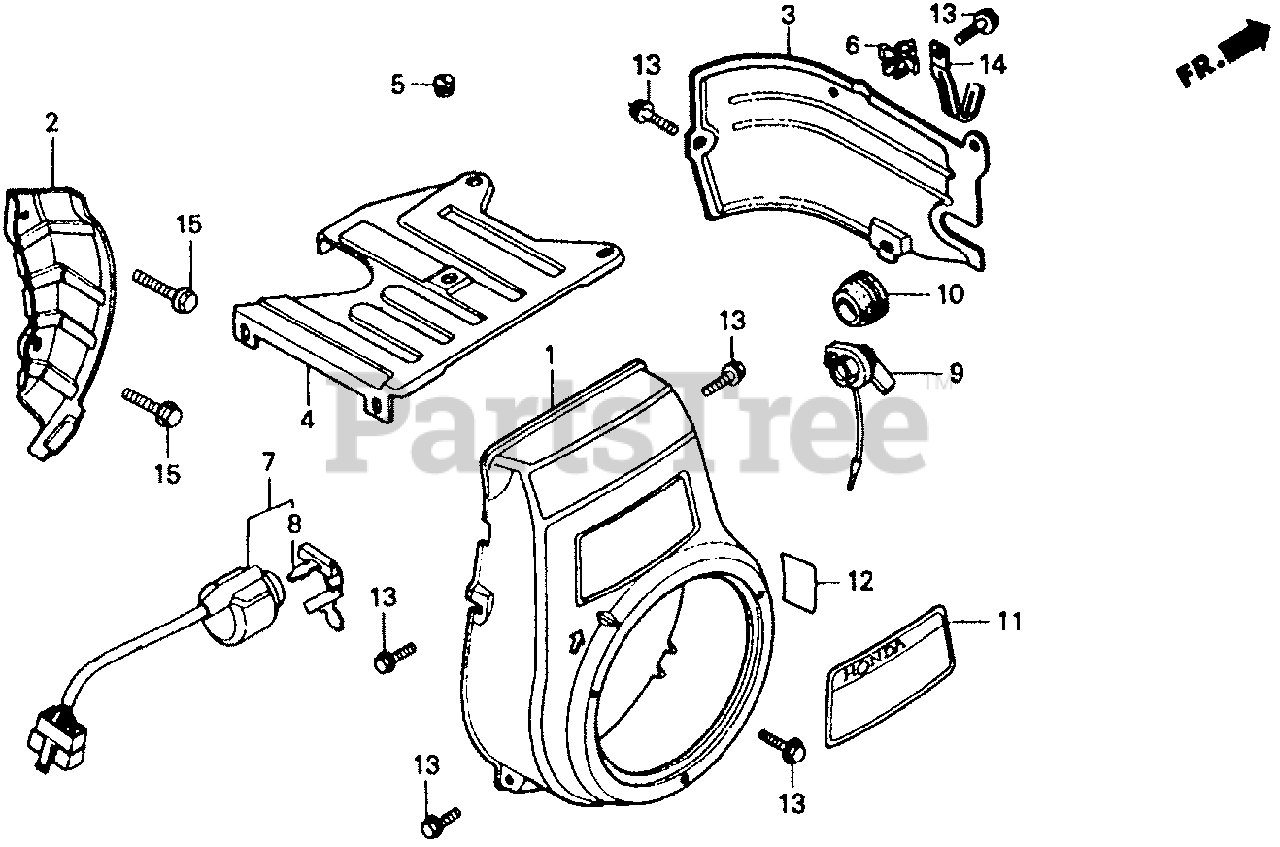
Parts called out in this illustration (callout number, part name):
1	COVER, FAN *R8* (BRIGHT RED)
2	PLATE, SIDE
3	SHROUD
4	COVER, TOP
5	GROMMET, TOP COVER
6	CLIP, IGNITION WIRE (8MM)
7	SWITCH ASSY., COMBINATION
8	KEY
9	SWITCH ASSY., ENGINE STOP
11	EMBLEM (ENGLISH/FRENCH/SPANISH)
12	MARK, OIL CAUTION
13	BOLT, FLANGE (6X12) (CT200)
14	CLIP, WIRE HARNESS
15	BOLT, FLANGE (8X20)
